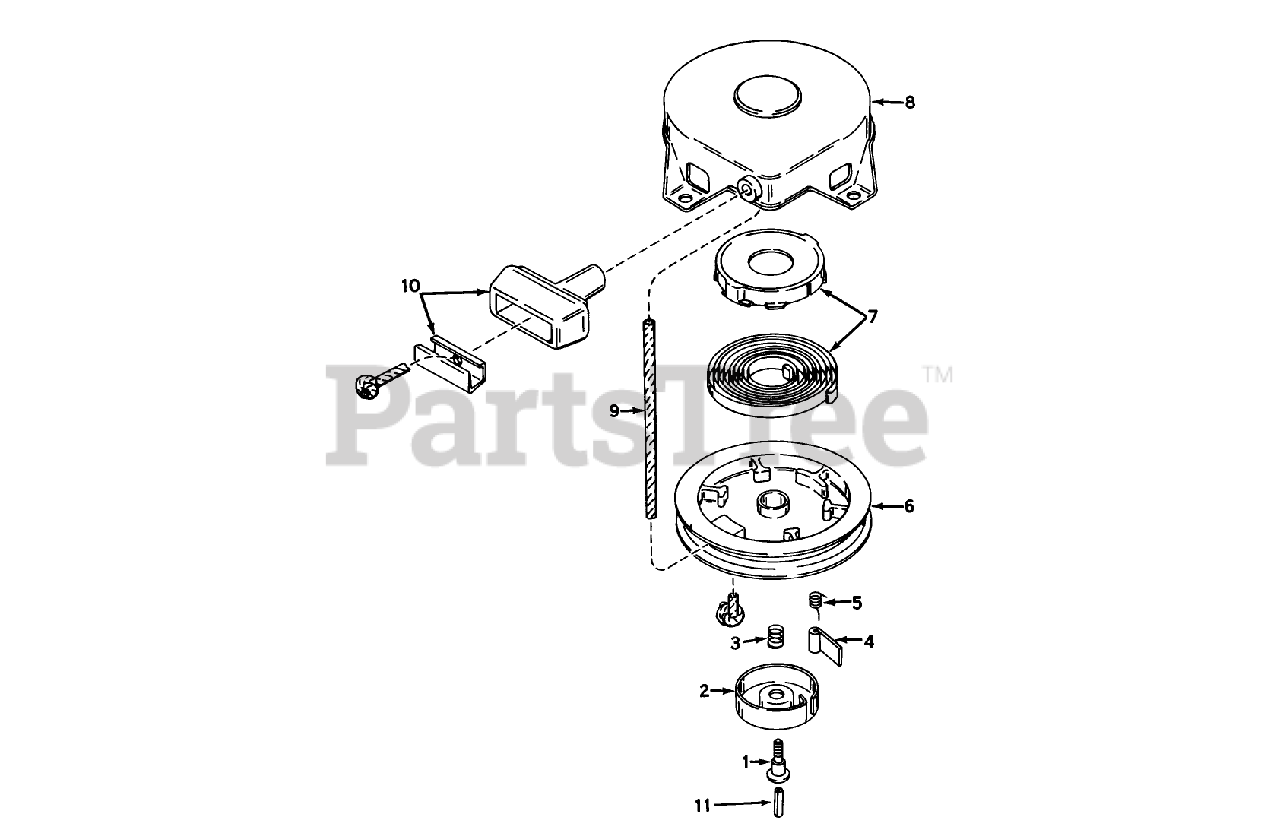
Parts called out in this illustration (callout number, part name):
1	Screw
2	Retainer
3	Spring-Brake
4	Dog-Starter
5	Spring-Dog
6	Pulley
7	Spring Keeper Assy
8	STARTER HOUSING ASSY
9	Rope-Starter
10	Assy., Starter
11	Centering
